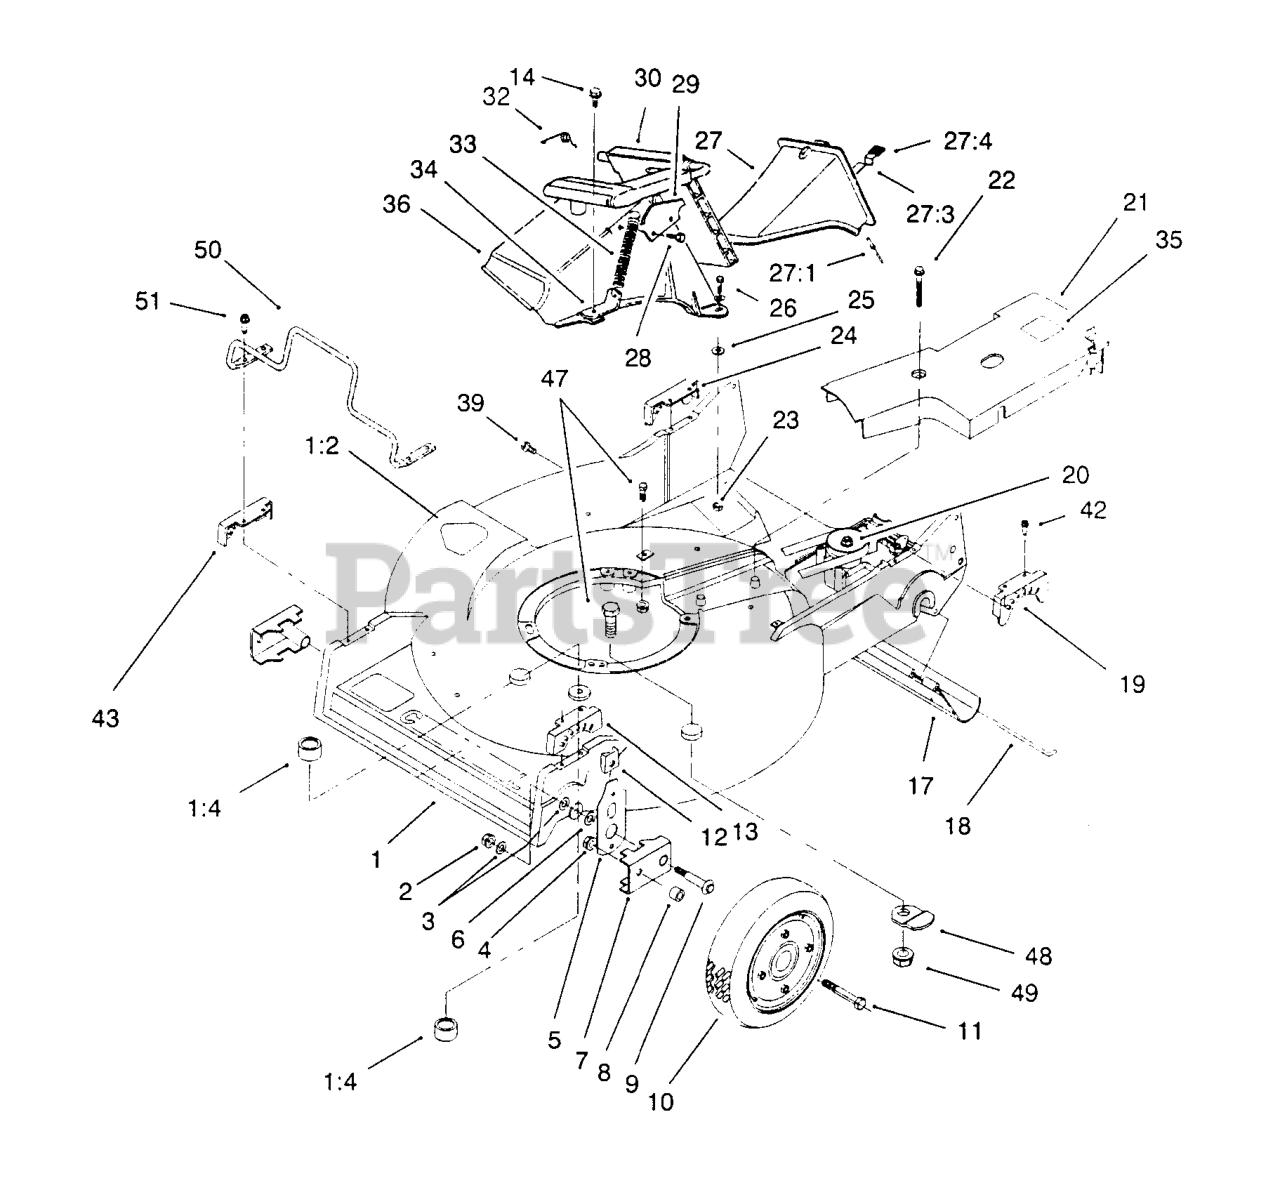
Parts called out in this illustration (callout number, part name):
1	HOUSING ASM
1:2	DECAL-DANGER
1:4	BEARING
2	NUT-LOCK
4	NUT-LOCK, CONE
5	FRONT SPRING ARM ASM
6	WASHER-THRUST
7	ARM-PIVOT, FRONT
8	SPACER-WHEEL
11	BOLT-CARR
12	KNOB-ARM
13	QUADRANT-FRONT, LH
14	SCREW-HWH
18	ROD-SHIELD
19	QUADRANT-REAR, LH
21	COVER-BELT
22	SCREW-HWH
23	NUT-LOCK, NI
24	QUADRANT-REAR, RH
25	WASHER-FLAT
26	SCREW-HH
27	DISCHARGE PLUG ASM
27:1	RIVET-HEAD, FLAT
27:3	LATCH-PLUG, DISCHARGE
27:4	GRIP-LATCH
28	SCREW-PLASTITE
29	LATCH-PLATE
30	DISCHARGE DOOR ASM
32	RETAINER-DOOR
33	SPRING-DOOR
34	BRACKET-SPRING
35	Label - Grease
36	TUNNEL-DISCHARGE
39	SCREW AND WASHER ASM
42	SCREW-HWHTF
43	QUADRANT-FRONT, RH
47	SCREW-HH
48	SHIELD-RETAINER
49	NUT-LOCK, NI
50	GUARD-ENGINE
51	SCREW-HWHTF
